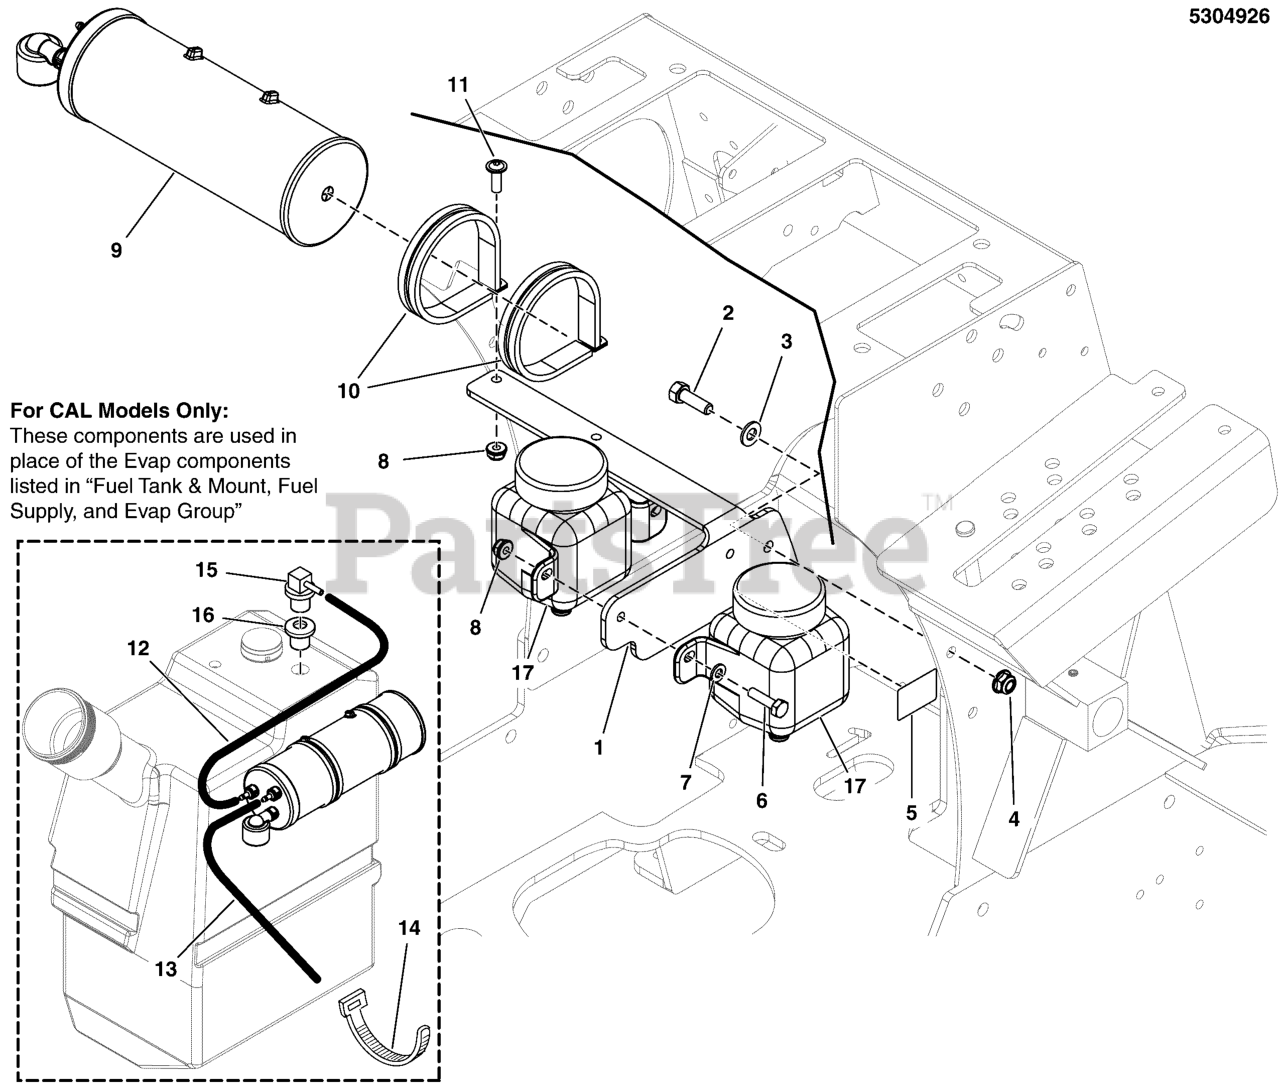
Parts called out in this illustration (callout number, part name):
1	PLATE, HYDRO BOTTLE MNT, SRSZ1,CAL - BLK
2	BOLT, 5/16-18 X 1 GD5 CZ
3	WASHER, 5/16" SAE
4	NUT, 5/16-18 HEX NYLOCK FLANGE
5	DECAL, HYDRAULIC OIL, 20W-50, 1" X 1.44"
6	BOLT, 1/4-20 X 1" GD5 CZ
7	WASHER, 1/4 SAE
8	NUT, 1/4-20 HEX NYLOCK FLANGE
9	CNSTR, CARB, 9 GAL
10	CLAMP, 3" ID, CUSHIONED, STAINLESS
12	HOSE, VAPOR, 5MM ID, 10.00 LG
13	HOSE, VAPOR, 5MM ID, 31.00 LG
14	TIE,SELF-LOCKING, 6"
15	REMOTE VENT ASSEMBLY
16	GROMMET (SV)
17	SEE HYDRAULIC GROUP
